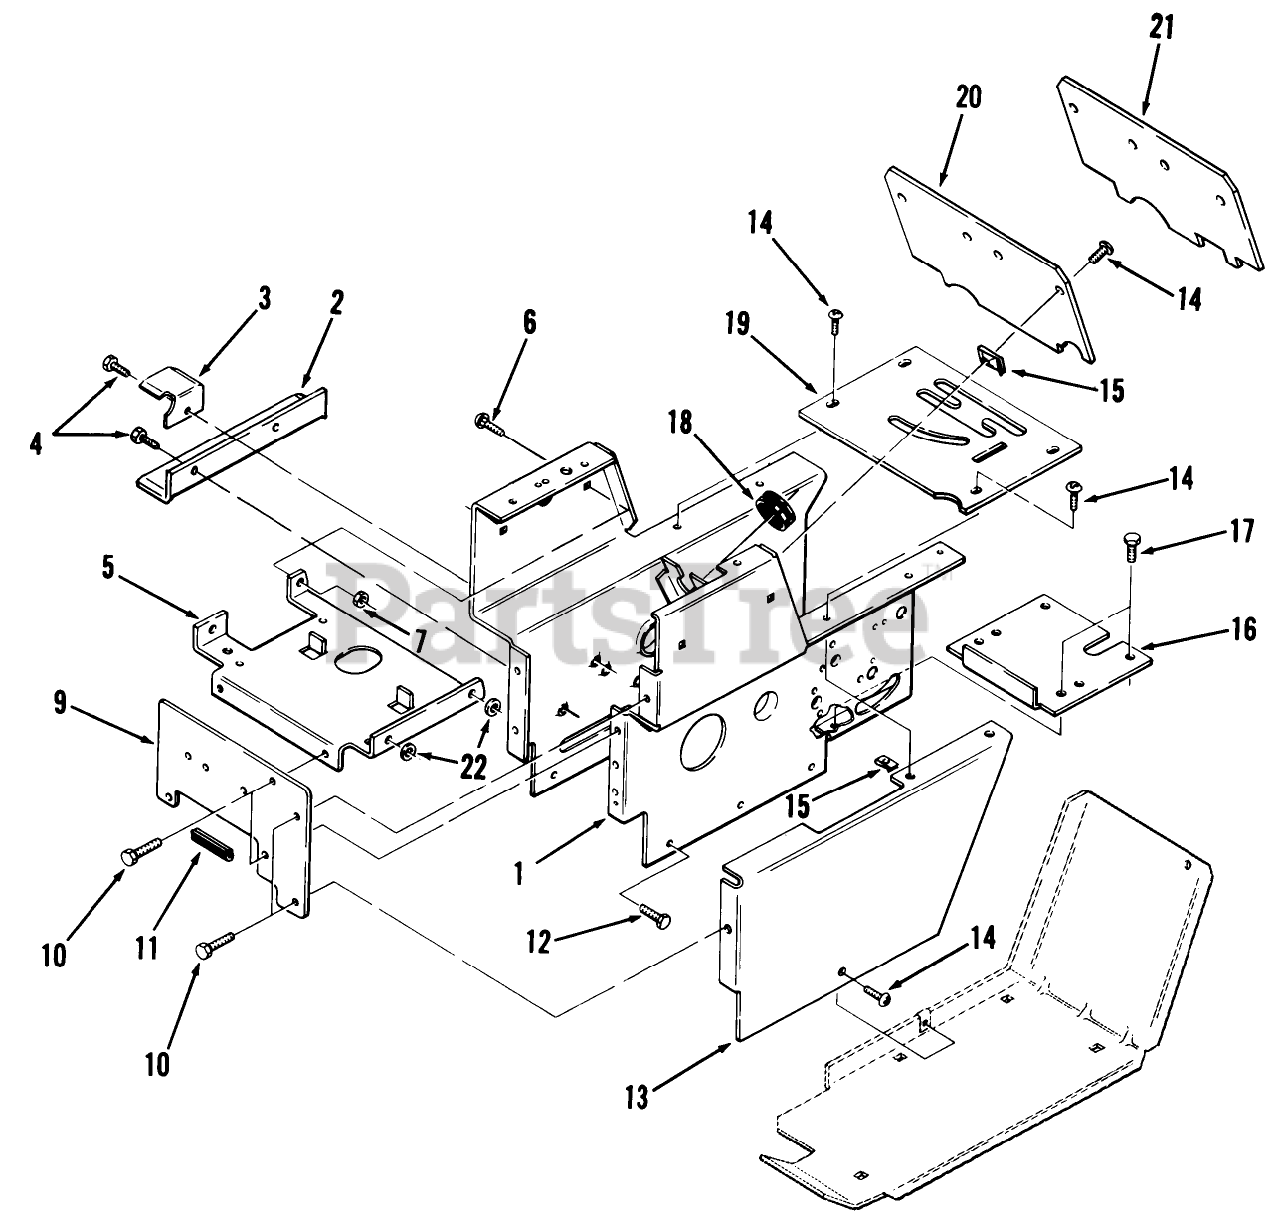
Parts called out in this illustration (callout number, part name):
2	ANGL-BLT GURD*B
3	BRCKET-BLT SUT*B
4	SCREW
10	SCREW
12	SCREW
17	SCREW
18	GROMMET
22	WASHER 5/16 SAE
